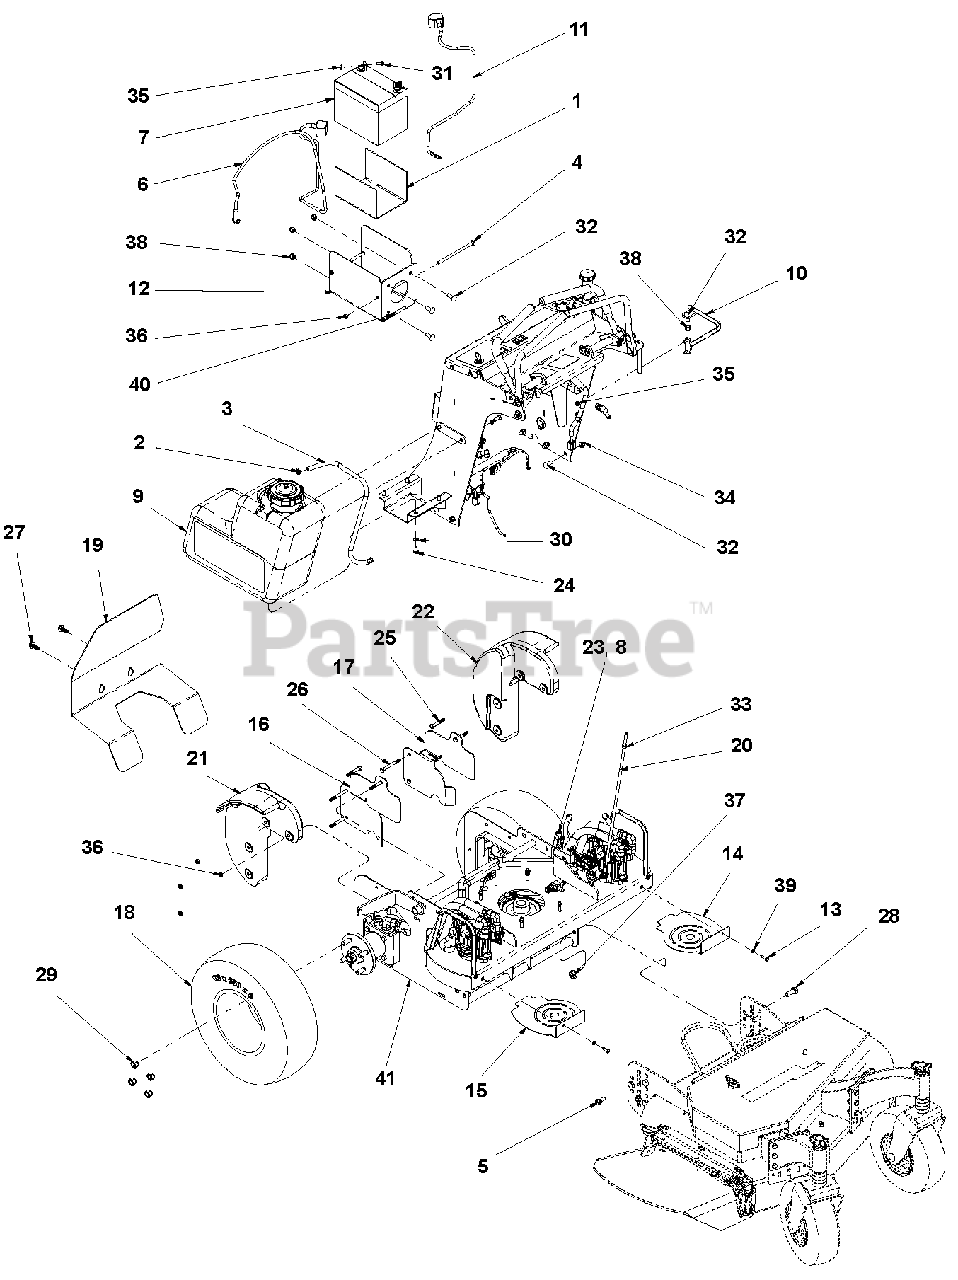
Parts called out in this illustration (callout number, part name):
1	Pad, Battery Insulator
2	Clamp, Hose (Red) #
3	Hose, 1/4" Id Low Perm Fuel 50
4	Cap Screw, 5/16" x 6"
5	Bolt, .50 x 1.06 x .375-16 Sld 5 Y
6	Cable, Battery Starter - 48"
7	Battery, 12V-U1-CCA 270 min
8	Pin, Clevis Spg 3/8" Yoke Spec Y
9	Tank, Fuel
10	Weldment, Reservior Guard
11	Cable, Battery - 25" Ground
12	Console Battery Bracket, w/Decal
13	Bolt, .25-20 x .750 Hex 5 Y
14	Shield, LH Pump
15	Shield, RH Pump
16	Shield, RH Motor w/Decal
17	Shield, LH Motor w/Decal
18	Assembly, Tire/Wheel 18/6.5 x 8 Slvr
19	Shield, Engine w/Decal
20	Rod, Control 5/16 x 22.75 Y
21	RH Cast Weight Machined
22	LH Cast Weight Machined
23	Clevis, .38-24 Adjustment
24	Bolt, Hex .25-20 x .75 Grade 5
25	Bolt, Hex .31-18 x .75 Grade 5
26	Bolt, .312-18 x 3.00 Hex 5 Y
27	Bolt, .38-16 x 1.00 Fgh 8 Y
28	Bolt, Hex .50-13 x 1.25 Grade 5
29	Nut, .50-20 Lug C
30	Washer, .313 Med Sprg Lock Y
31	Bolt, .25-20 x .625 Wsh Y
32	Bolt, Round Head Square Neck .38-16x1.00 G 5
33	Nut, Hex .312-24
34	Nut, Flange .375-16
35	Nut, Locking-Flange .250-20
36	Nut, Locking-Nylon .312-18
37	Nut, Spin Lock-Flange .50-13
38	Nut, Locking-Nylon .38-16
39	Washer, .313 Medium Spring Lock Y
40	Trim, Rubber Edge 2"
41	Power Unit 19 Narrow (see page 12)
